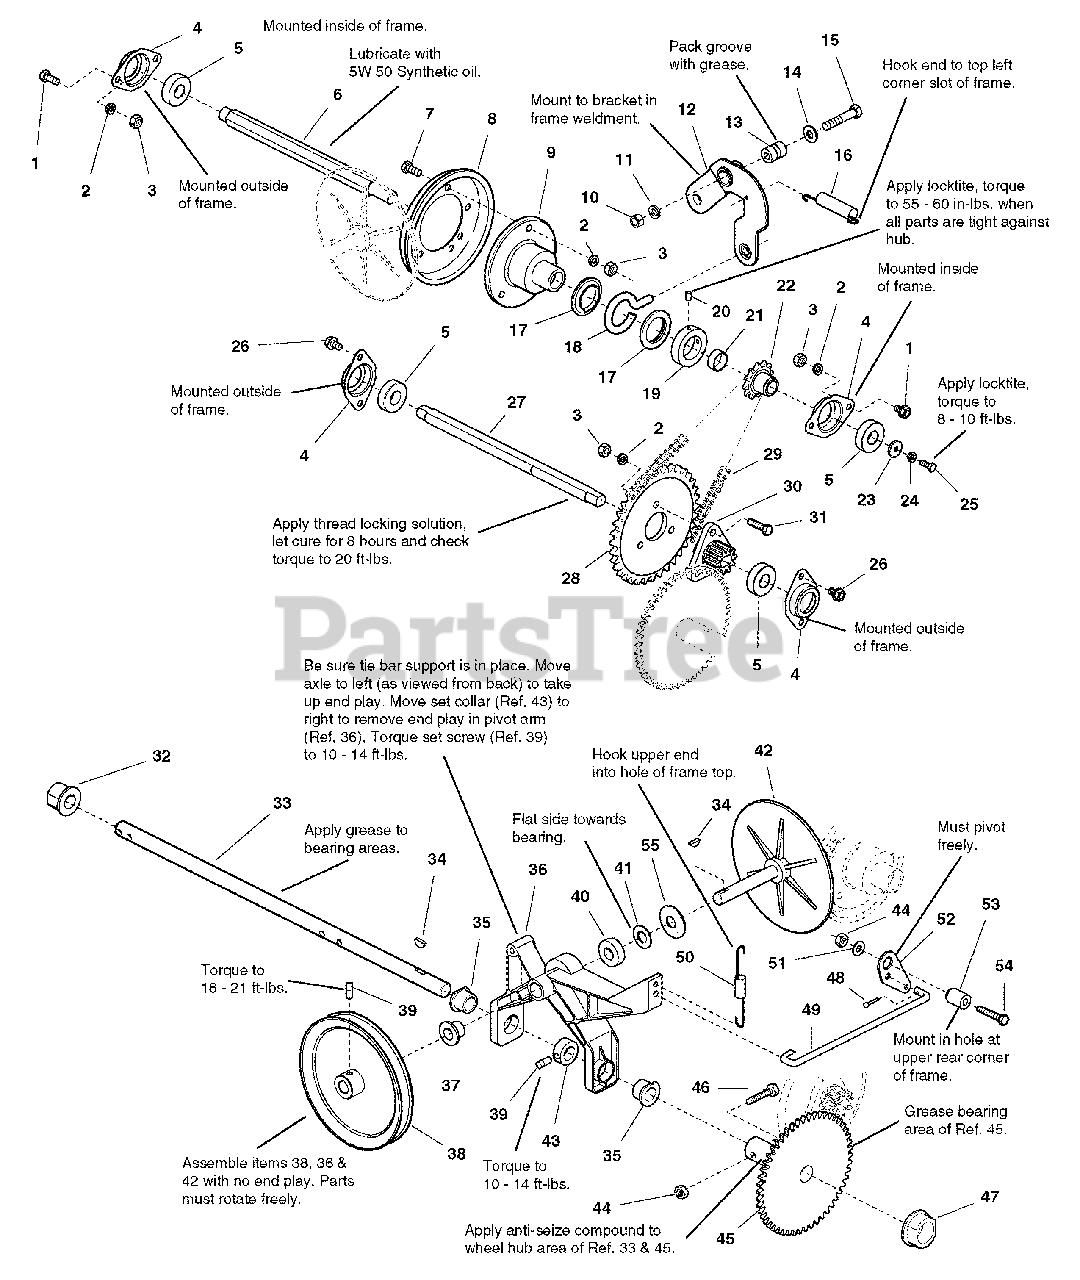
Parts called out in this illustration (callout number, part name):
1	CAPSCREW, Hex Head, 5/16-18 x 5/8
2	LOCKWASHER, 5/16
3	NUT, Hex, 5/16-18
4	RETAINER, Bearing
7	CAPSCREW, Hex Head, 5/16-18 x 3/4
8	DISC, Friction
9	HUB, Friction Disc
10	NUT, Hex, 3/8-16
11	LOCKWASHER, 3/8
12	ARM ASSEMBLY, Shift w/Bushings
13	BUSHING, Spacer
14	WASHER, Flat, 13/32
15	CAPSCREW, Hex Head, 3/8-16 x 2
16	SPRING
17	COLLAR, Thrust
20	SETSCREW, Square Head, 1/4-20 x 1/2
22	SPROCKET, 10 Tooth
23	WASHER, Flat, 1/4
24	LOCKWASHER, 1/4
25	CAPSCREW, Hex Head, 1 /4-20 x 5/8
26	CAPSCREW, Taptite, 5/16-18 x 1/2
28	SPROCKET, 36 Tooth
29	CHAIN, Drive, 40
30	GEAR & BEARING ASSEMBLY., 10 Tooth
31	CAPSCREW, Hex Head, 5/16-18 x 1
34	KEY, Woodruff, 3/16 x 5/8
36	ARM ASSEMBLY, Pivot w/Bushings, (Includes Ref. 35, 37 & 40)
38	PULLEY, Traction
39	SETSCREW, Square Head, 5/16-18 x 1/2
41	WASHER, 5/8
42	DRIVE DISC W/SPINDLE
43	SET COLLAR
44	NUT, Hex, Lock, 5/16-18
45	GEAR & HUB ASSEMBLY, w/Bushing, 50 Tooth
46	CAPSCREW, Hex Head, 5/16-18 x 1-1/2
47	BUSHING, Axle
48	PIN, Cotter, 1/8 x 3/4
51	WASHER, Flat, 11/32
53	BUSHING, Pivot
54	CAPSCREW, Hex Head, 5/16-18 x 1-3/4
55	WASHER
